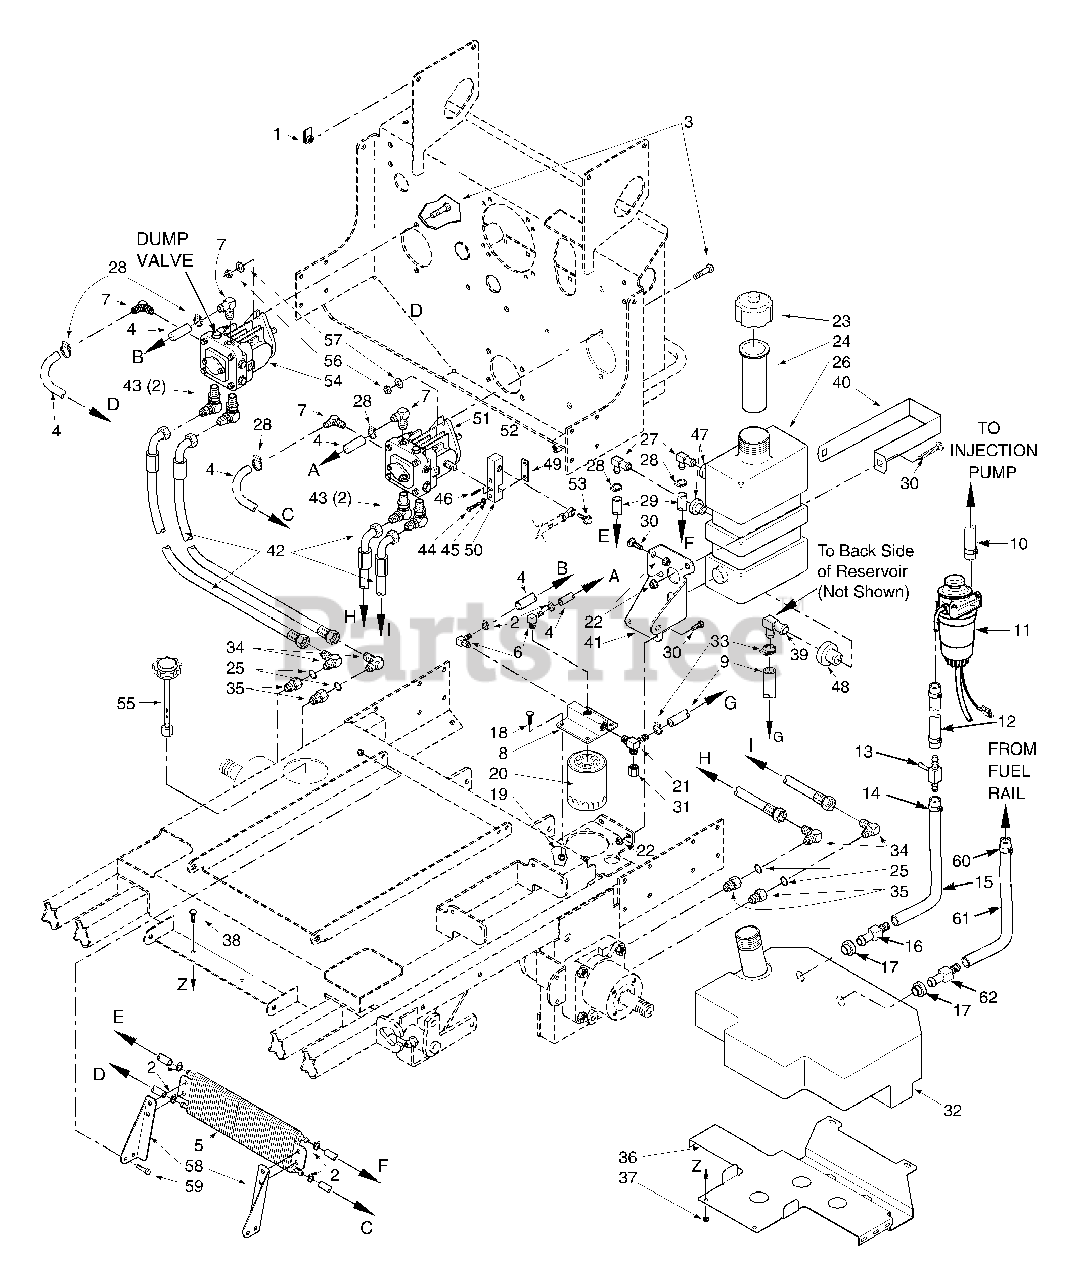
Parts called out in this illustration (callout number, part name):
1	U-Nut 1/4-20
2	Hose Clamp, 0.69 dia.
3	Bolt, Hex Head 1/4-20 x 2.0"
4	Hose, 3/8" ID Pushlock - (order by inch)
5	Cooler, Oil
6	Elbow, 90 Degree - 9/16 O-ring x 3/8 Hose
7	Elbow, 90 Degree - 3/4 O-ring x 3/8 Hose
8	Oil Filter Base
9	Hose Assembly, 1/2" ID (Tank to Filter Base)
10	Fuel Hose to Carb., 1/4" ID (order by inch)
11	Fuel Filter
12	Fuel Hose, 1/4" ID. (order by inch)
13	Valve, Shutoff
14	Clamp, Fuel Hose 5/16 ID
15	Fuel Hose, 5/16" ID. (order by inch)
16	Hose Fitting
17	Bushing
18	Bolt, Hex Head 5/16-18 x1.0" Zinc
19	Nut, Serrated Flange 5/16-18
20	Oil Filter
21	Tee, 3/4 O-ring x JIC x 1/2" Hose
22	Nut, Hex Elastic Stop 1/4-20
23	Cap, Hydraulic Tank
24	Insert, Filler Neck
25	O-Ring
26	Oil Reservoir Assembly
27	Elbow, 90 Degree, 9/16-18 JIC x 9/16 O-Ring
28	Hose Clamp, 0.69 dia.
29	Hose, 3/8" ID, Pushlock (order by inch)
30	Screw, Phillips Head, 1/4-20
32	Fuel Tank Assembly
33	Clamp, Hose
34	Elbow, 90 Degree, 7/8-14 THD
35	Bushing, 7/8-14 JIC x 3/4-16 O-Ring
36	Support Bracket, Fuel Tank
37	Nut, 5/16-18 Serrated Flange
38	Bolt, Carraige 1/4-20 x 3/4"
39	Elbow, 90 Degree
40	Strap, Hydraulic Tank
41	Support Bracket, Hydraulic Tank
42	Hose Assembly, Pump
43	Elbow, 90 Degree 7/8-14 Thread
44	Bolt, Hex Head, 1/4-20 x 1-14"
45	Lockwasher, 1/4" Spring
46	Roll Pin, Spring 3/16 x 3/4"
47	Bushing, .56 Dia.
48	Bushing, .78 Dia.
49	Clamp Plate, Pump Control
50	Block, Pump Control
51	Pump, Left Hand, BDP-21L-305
52	Nut, Hex, Elastic Stop 3/8-16
53	Bolt, Hex Head, 3/8-16 x 1-1/4
54	Pump, Right Hand, BDP-21L-403
55	Cap, Fuel Tank W/Gauge
56	Nut, Hex Elastic Stop 3/8-16
57	Flatwasher, 3/8" (.391 x .938 x .105) Grade 8
58	Mounting Bracket - LH, Oil Cooler
59	Bolt, Hex Head 5/16-18 x 3/4"
60	Clamp, 3/16 Hose
61	Hose, 3/16" I.D. (order by inch)
62	Hose Fitting, Straight DAPCO
